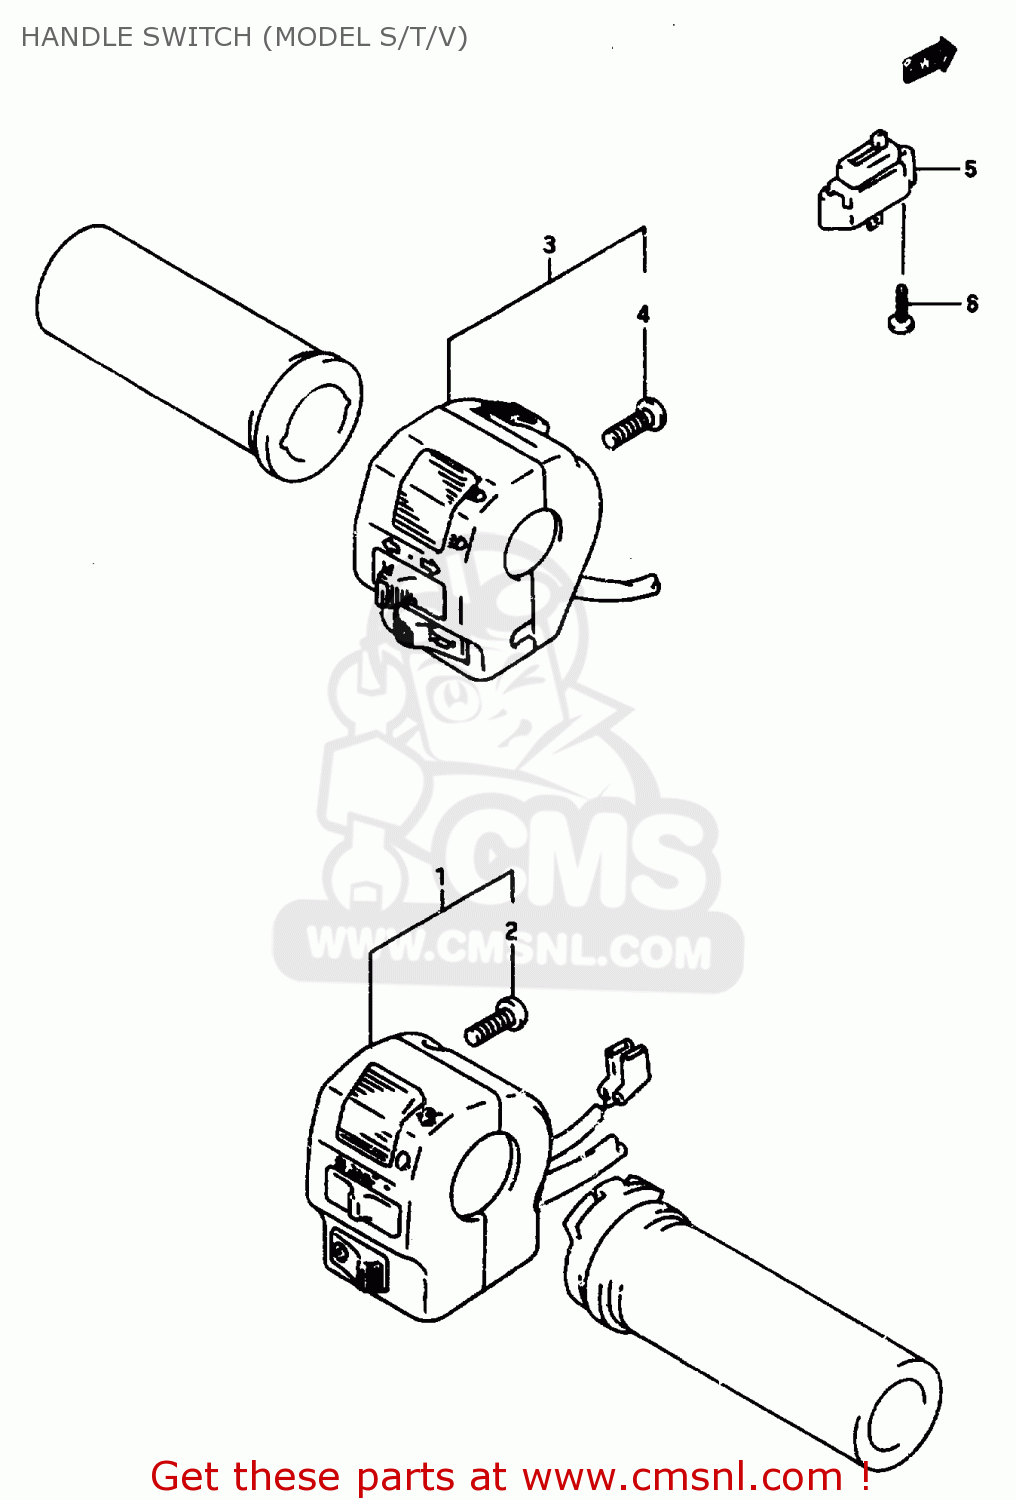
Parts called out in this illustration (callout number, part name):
1	SWITCH ASSY,HANDLE,R
2	SCREW
3	SWITCH,HANDLE,
4	SCREW
5	SWITCH ASSY,CLUTCH
6	SCREW
